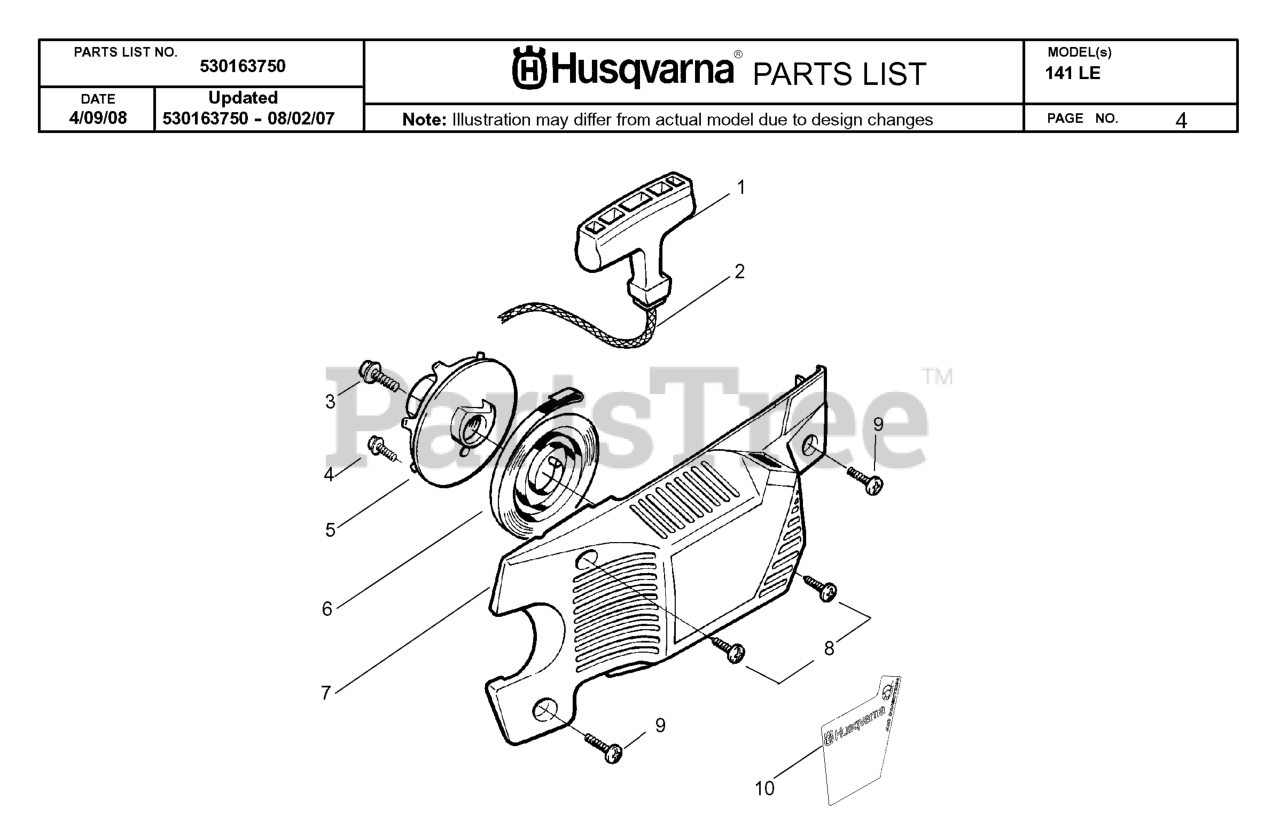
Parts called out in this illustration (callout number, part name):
1	STARTER HANDLE GRAY
5	PULLEY 36/41
6	RETURN SPRING
7	FAN HOUSING ASSEMBLY
8	SCREW,STRTR CVR 36/41
10	Decal - Fan Housing
